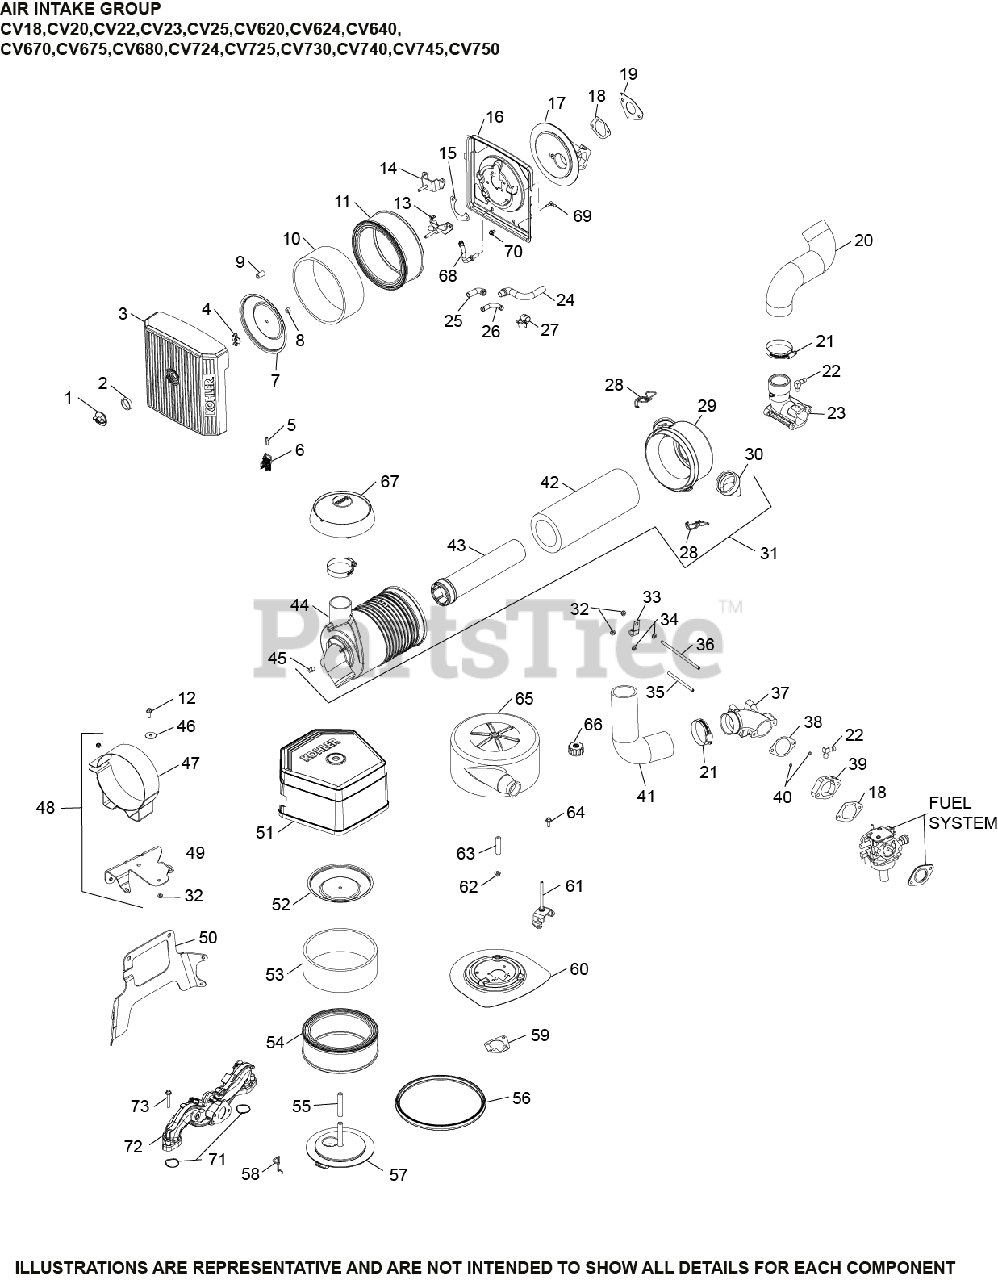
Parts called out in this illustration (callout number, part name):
12	SCREW, THREAD FORMING
12	SCREW, FLG M6X1.0X16
18	GASKET, AIR CLEANER BASE
21	CLAMP, HOSE-USE 25 237 21-S
22	CONNECTOR, HOSE
28	CLIP - USE 62 154 07-S
29	COVER ASSEMBLY, AIR CLEANER
30	VALVE, DUST EJECTOR
31	AIR CLNR, CANISTER-USE 25 048 17-S
32	NUT, LOCK M6X1.0
35	STUD, M6X1.0X180
42	ELEMENT, AIR FILTER - PRIMARY
43	ELEMENT, AIR FILTER - SAFETY
44	HOUSING, HD AIR CLEANER
45	PLUG, PIPE
46	WASHER, FLAT 1/4"
47	BRACKET, AIR CLEANER
49	BRACKET, AIR CLEANER MOUNTING
50	BRACKET, MAIN SUPPORT
67	HOOD, INLET
